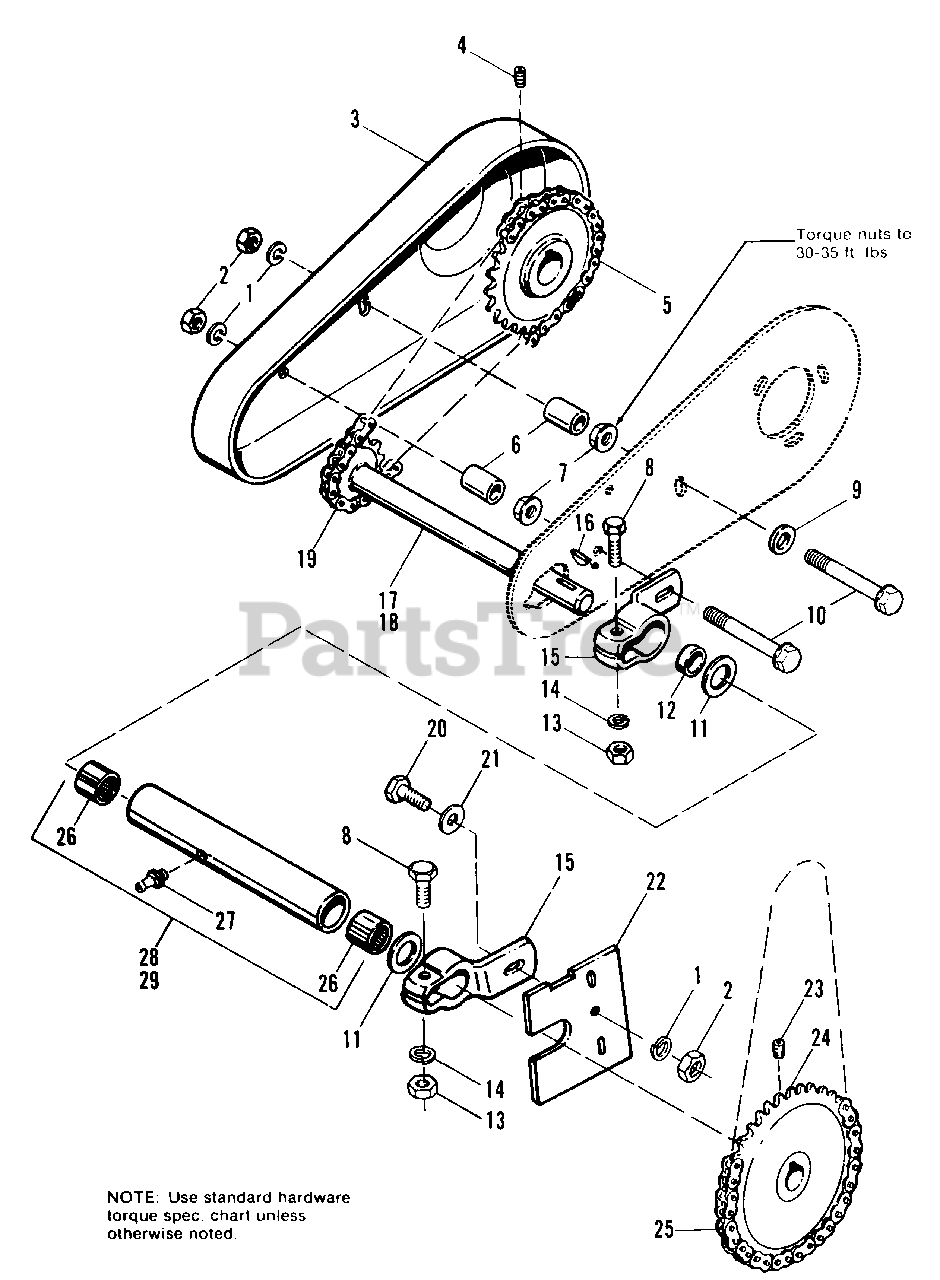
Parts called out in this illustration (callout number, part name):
1	LOCKWASHER, 3/8
2	NUT, Hex, full, 3/8-16
3	GUARD, Chairs
4	SETSCREW, 5/16-18 x 1-1/2
5	SPROCKET, Rotor
7	NUT, Flange, Whiz, 3/8-16
8	CAPSCREW, Hex Hd., 5/16-18 x 1-3/4
10	CAPSCREW, Flange, Whiz, 3/8-16 x 2-1/4
13	NUT, Hex Full, 5/16-18
14	LOCKWASHER 5/16
15	CLAMP, Housing
16	KEY, Woodruff, #9
17	SHAFT ASSY., (1690379 & 1690380 Only)
17	SHAFT ASSY., (1690442 Only)
18	CHAIN, Auger Driver
19	CAPSCREW, Hex Hd., (3/8-16 x 7/8)
20	WASHER, Plain, 3/8
21	PLATE, Adjust
22	SETSCREW, 5/16-18 x 5/16
24	CHAIN, Drive Sprocket
25	BEARING, Needle
26	FITTING Grease
27	HOUSING, W/Bearings (1690379 & 1690380 Only)
27	HOUSING, W/Bearings (1690442 Only)
